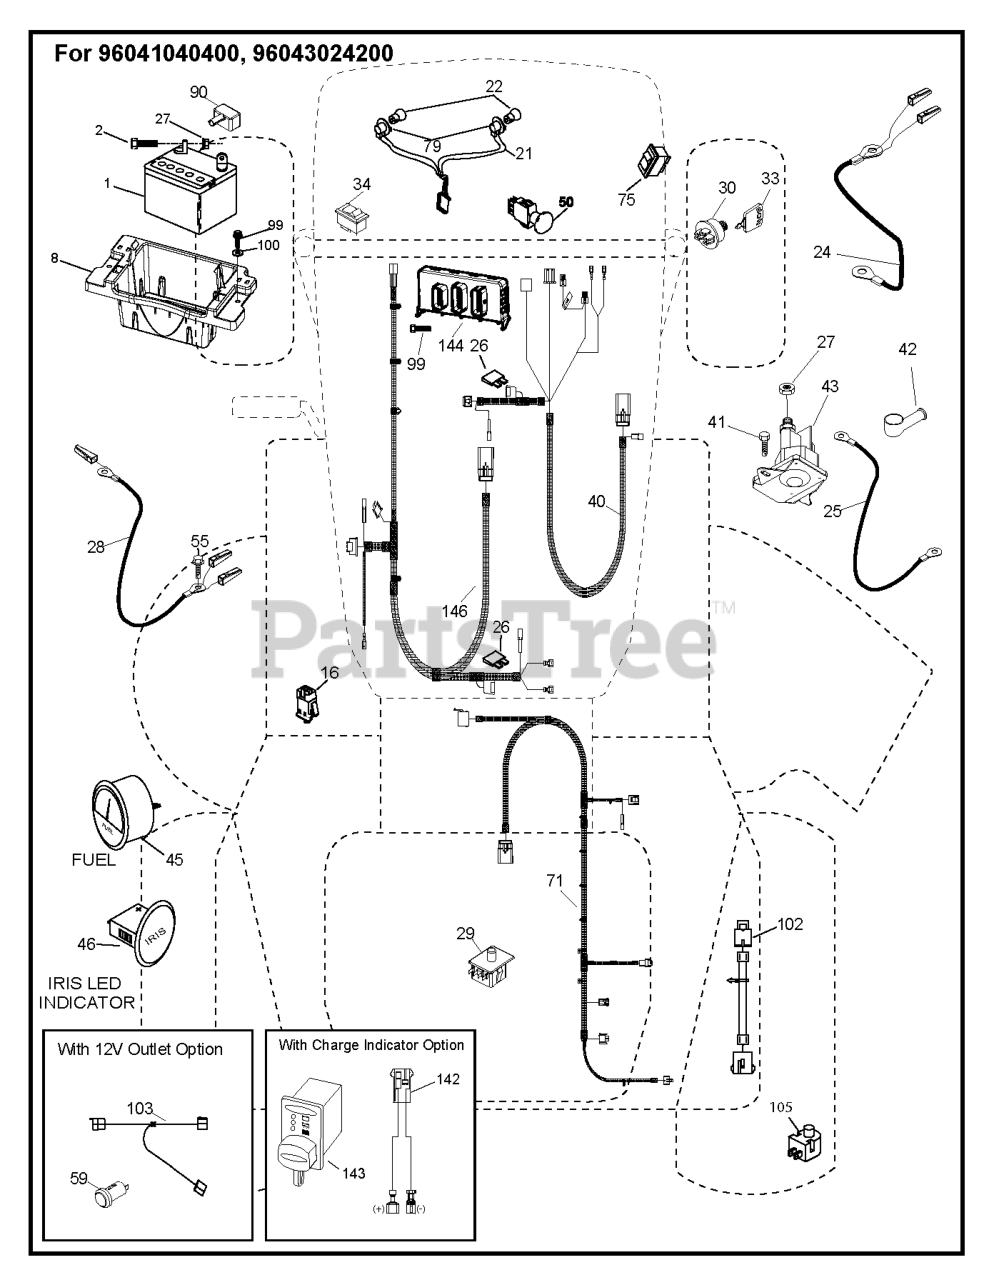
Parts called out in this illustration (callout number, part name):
1	Battery 12 Volt 25 Amp
2	BOLT.HEX.1/4.X.3/4.DICHROMATE
8	TRAY.BATTERY BOX.FRONT
16	SWITCH INTERLOOK PUSH-IN
21	HARNESS LIGHT ASSY TRACTOR,
21	HARNESS.LIGHT W/4152J BULBS
24	PRIMARY CABLE POSITIVE, TWO HA
25	CABLE.STARTER.8GA.17.5
26	FUSE 20AMP
27	NUT
28	GROUND CABLE TWO HARNESS TAPS,
29	SWITCH SEAT, 4 PIN NC/NO
30	SWITCH.IGN.DELTA.W.LGH.ROS
33	KEY.CHAIN.BLISTER.PACK.GEN.INT
40	WIRING ASSY DASH, IRIS, 300, T
41	SCREW
42	TERMINAL COVER
43	SOLENOID.STARTER.BRASS.PLUNGER
45	GAUGE.FUEL.LEVEL. ROUND.2"
46	GAUGE.INDCTR.RND.2"FARIA.6ICNS
46	GAUGE.6LED.IRIS.ROUND.2"
50	SWITCH.PTO.8TERMINAL.STD.BLK
55	SCREW 5/16"
71	WIRING ASSY CHASSIS, IRIS, 300
75	SWITCH.ON/OFF.(DIFF.LOCK)
79	BULB HOLDER ASM.
90	COVER.TERMINAL.BATTERY
99	SCREW HEXWSHR 1/4-20X3/4
102	HARNESS PIGTAIL PCH TEX ROS
105	REVERSE SWITCH
144	CONTROL.UNIT.RIDE.ON.IRIS.BASE
146	WIRING ASSY ENGINE, IRIS, 300,
